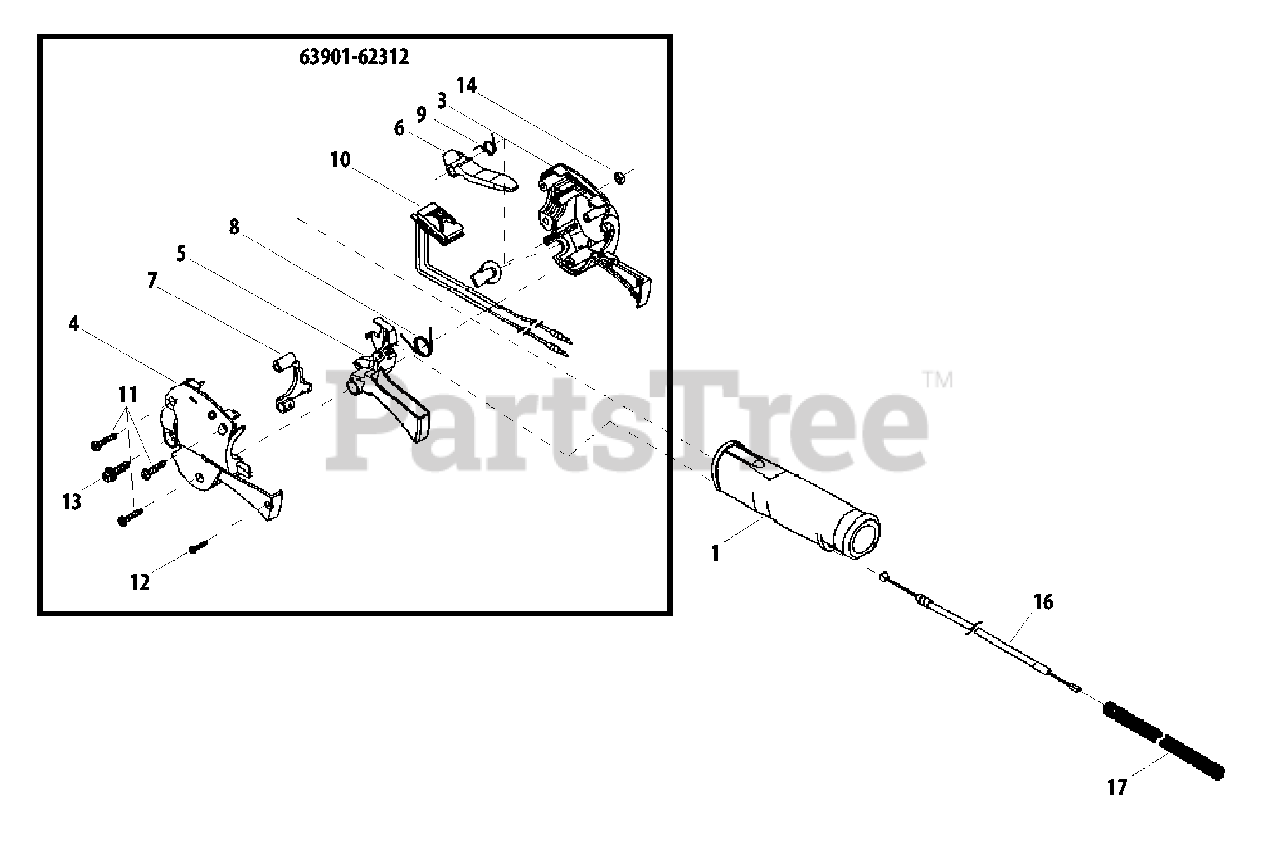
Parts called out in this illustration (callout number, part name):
1	GRIP
3	CONTROL HANDLE - RIGHT
4	CONTROL HANDLE - LEFT
5	TRIGGER, THROTTLE
6	LEVER, LOCK
7	LOCKOUT, THROTTLE
8	SPRING, THROTTLE RETURN
9	SPRING, THROTTLE LOCKOUT
10	SWITCH, ON-OFF
11	SCREW, TAPPING M4×20
12	SCREW, TAPPING 3×14
13	SCREW M5×20
14	NUT M5
15	PLUG
16	CABLE, THROTTLE
17	TUBE, PLASTIC PROTECTIVE
63901-62312	THROTTLE LEVER ASSY
